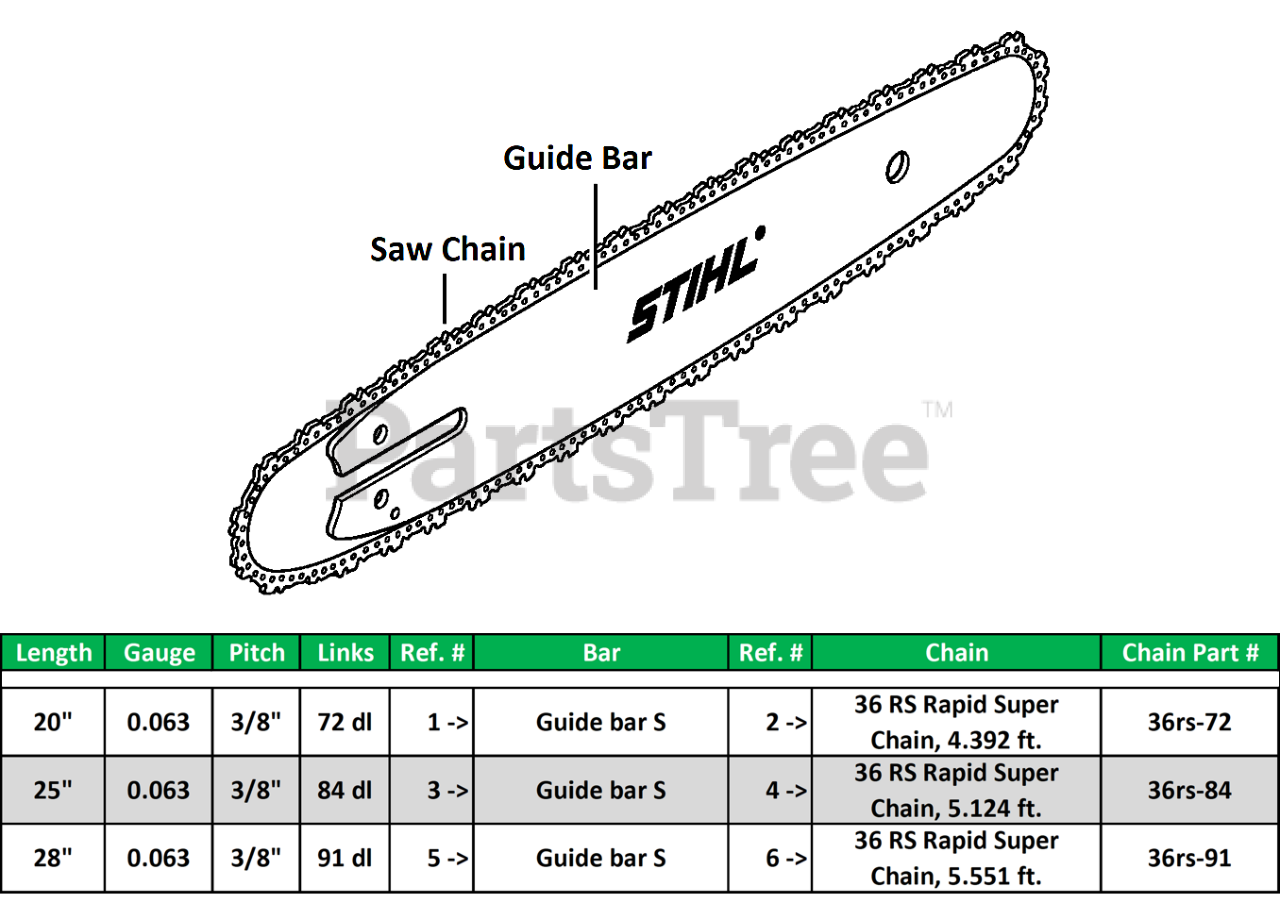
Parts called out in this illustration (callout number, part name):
1	Guide bar S 50cm/20" 1,6mm/0.063" 3/8"
2	36 RS Rapid Super Chain, 4.392 ft.
3	Guide bar S 63cm/25" 1,6mm/0.063" 3/8"
4	36 RS Rapid Super Chain, 5.124 ft.
5	Guide bar S 71cm/28" 1,6mm/0.063" 3/8"
6	36 RS Rapid Super Chain, 5.551 ft.
